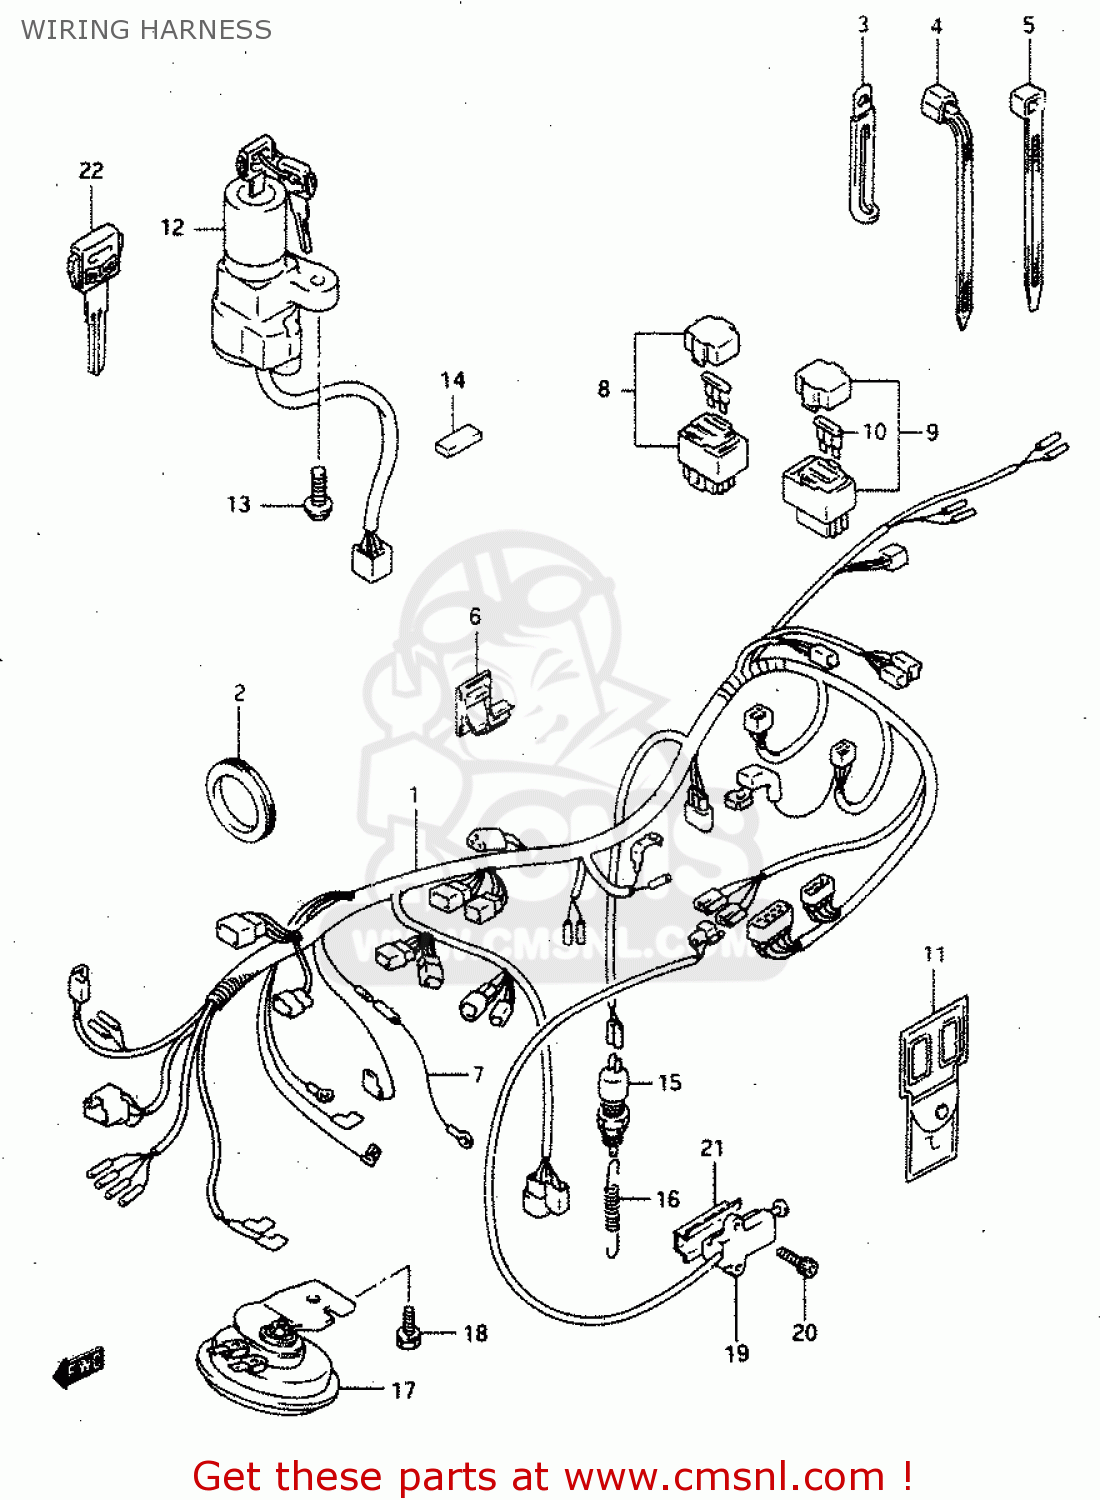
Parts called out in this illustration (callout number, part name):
1	HARNESS,WIRING
2	GROMMET
3	CLAMP
4	CLAMP(L:95)
5	CLAMP(L:95)
6	CLAMP
7	WIRE,LEAD
8	CASE ASSY, FUSE NO.2
9	BOX ASSY, FUSE
10	FUSE(5A)
11	FUSE SET,SPARE
12	LOCK ASSY,STEE
13	SCREW(6X18)
14	PROTECTOR(170X95X3.0)
15	SWITCH ASSY,STOP LAMP
16	SPRING
17	HORN ASSY
18	BOLT
19	SWITCH ASSY,SIDE STAND WARNING
20	BOLT
21	SHEET,HEAT PROTECTION
22	KEY,BLANK
